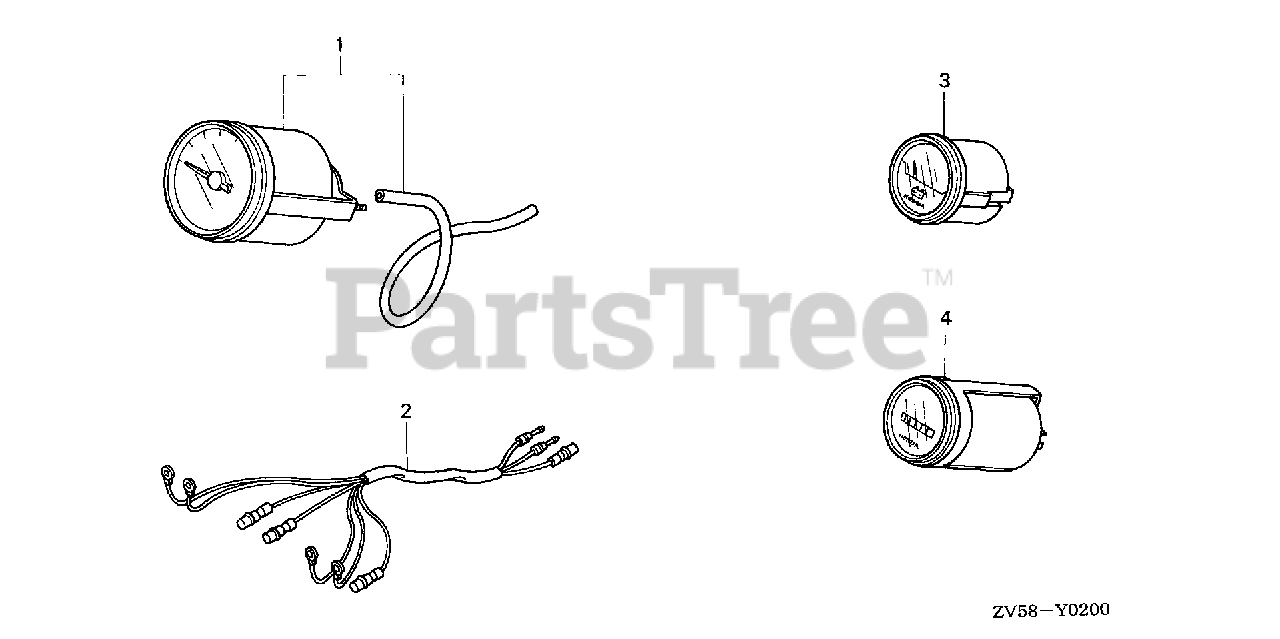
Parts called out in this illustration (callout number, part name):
1	SPEEDOMETER KIT
2	HARNESS ASSY., METER (B)
3	METER ASSY., VOLT (NOT AVAILABLE: USE 37453-ZW5-000ZA)
4	METER ASSY., HOUR L.C.D.
